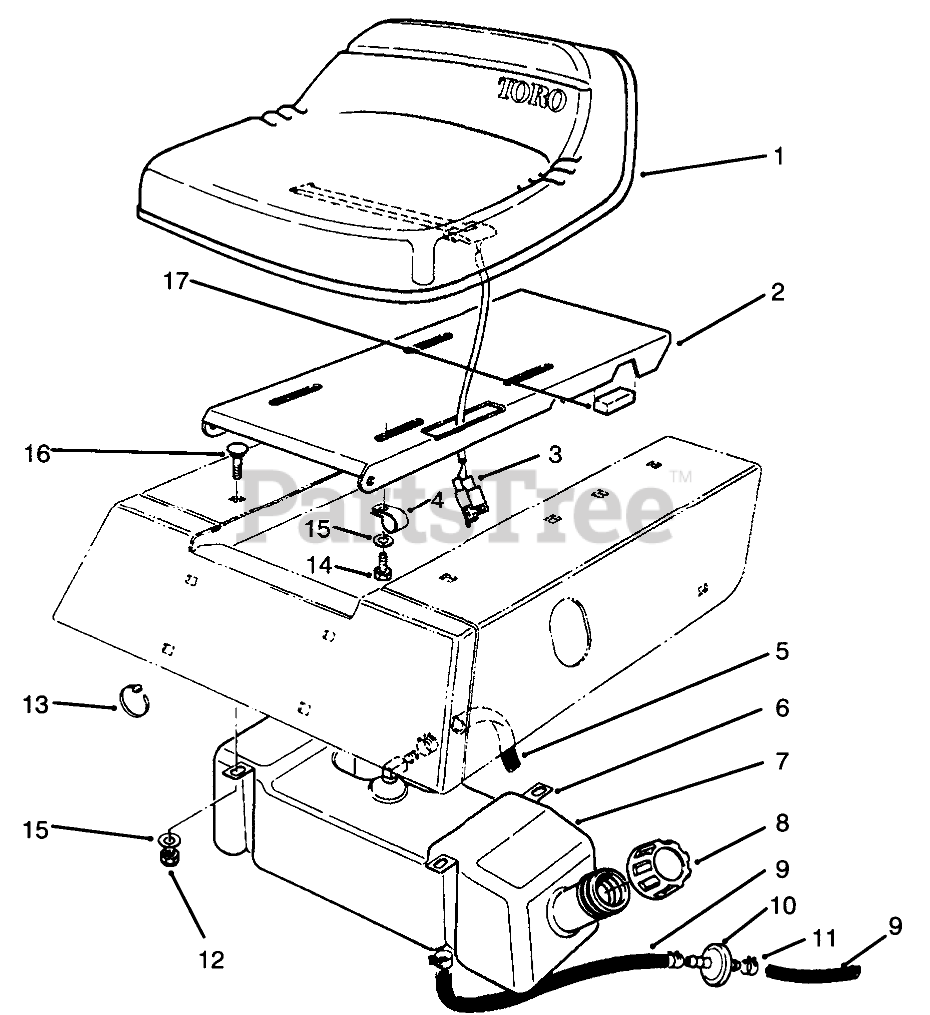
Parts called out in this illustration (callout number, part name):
1	Seat
2	BASE - SEAT
3	SWITCH-SEAT
4	CLIP-FUEL LINE
5	HOSE-FUEL
6	STRAP-GAS TANK
7	TANK-GAS
8	GAS CAP ASM
9	HOSE-FUEL
10	FILTER-FUEL
11	CLAMP-HOSE
12	NUT-LOCK, NI
13	TIE-CABLE
14	SCREW-HH
15	WASHER-PLAIN
16	SCREW-CARR
17	PAD-ISOLATOR
